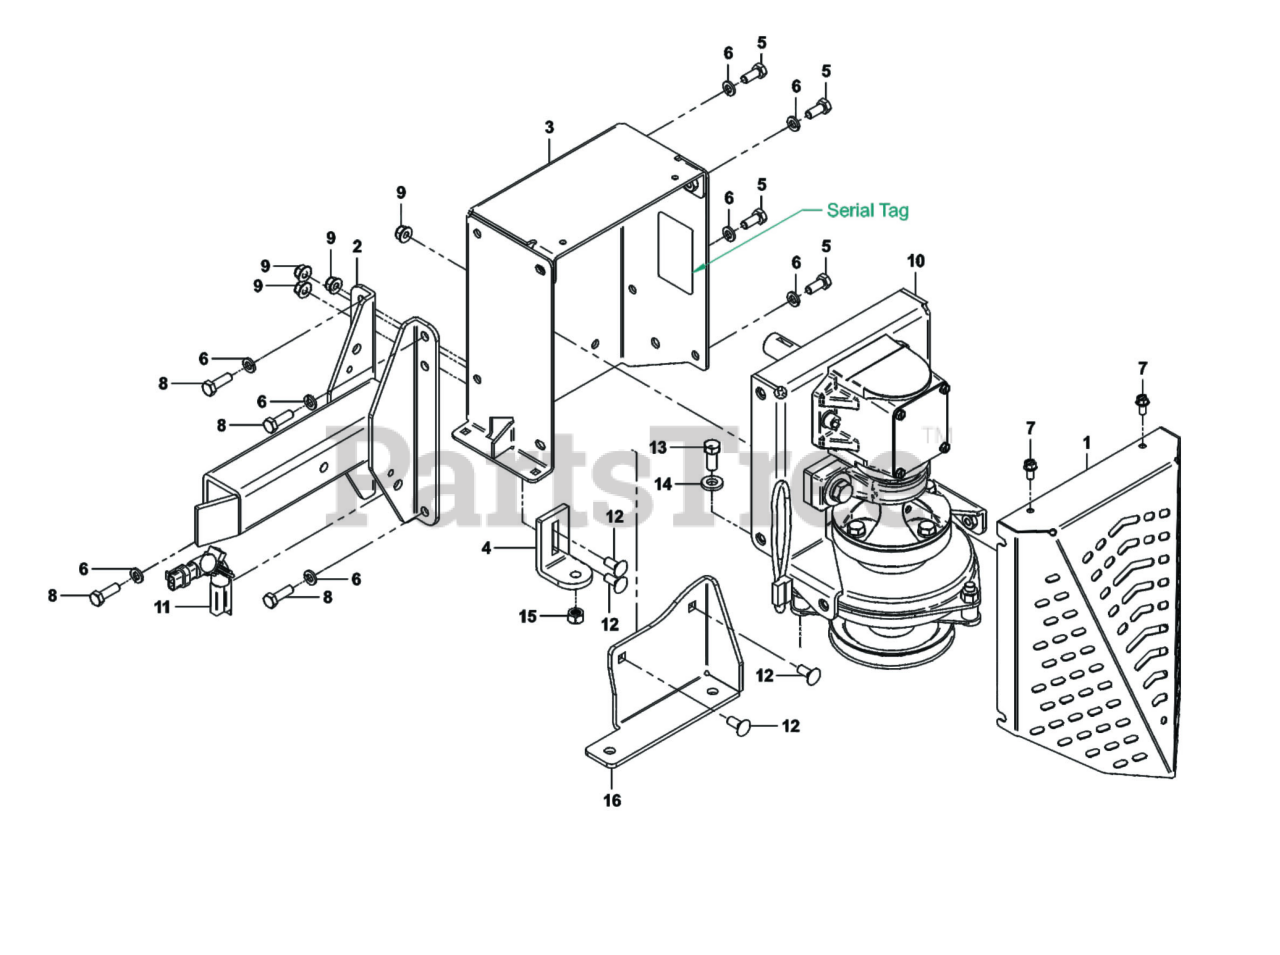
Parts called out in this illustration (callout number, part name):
1	DRIVE GUARD
2	DRIVE ARM ASSEMBLY
3	HOUSING MOUNT ASSEMBLY
4	ANTI-ROTATION BRACKET
5	HEX SCREW HEAD 5/1
6	LOCK WASHER 5/16"
7	HEX SCREW HEAD 1/4
8	HEX SCREW HEAD 5/1
9	NUT-FLANGE LOCK 5/
10	MOUNTED DRIVE ASSEMBLY
11	JUMPER HARNESS (W/DIODE)
12	SCREW 5/16"-18 X .75" GR8
13	SCREW 3/8"-16 x .875" (GR8)
14	FLAT WASHER
15	REVERSE GD "C" LOCK NUT (3/8-16)
16	PLATE-IDLER ASSY MOUNT
